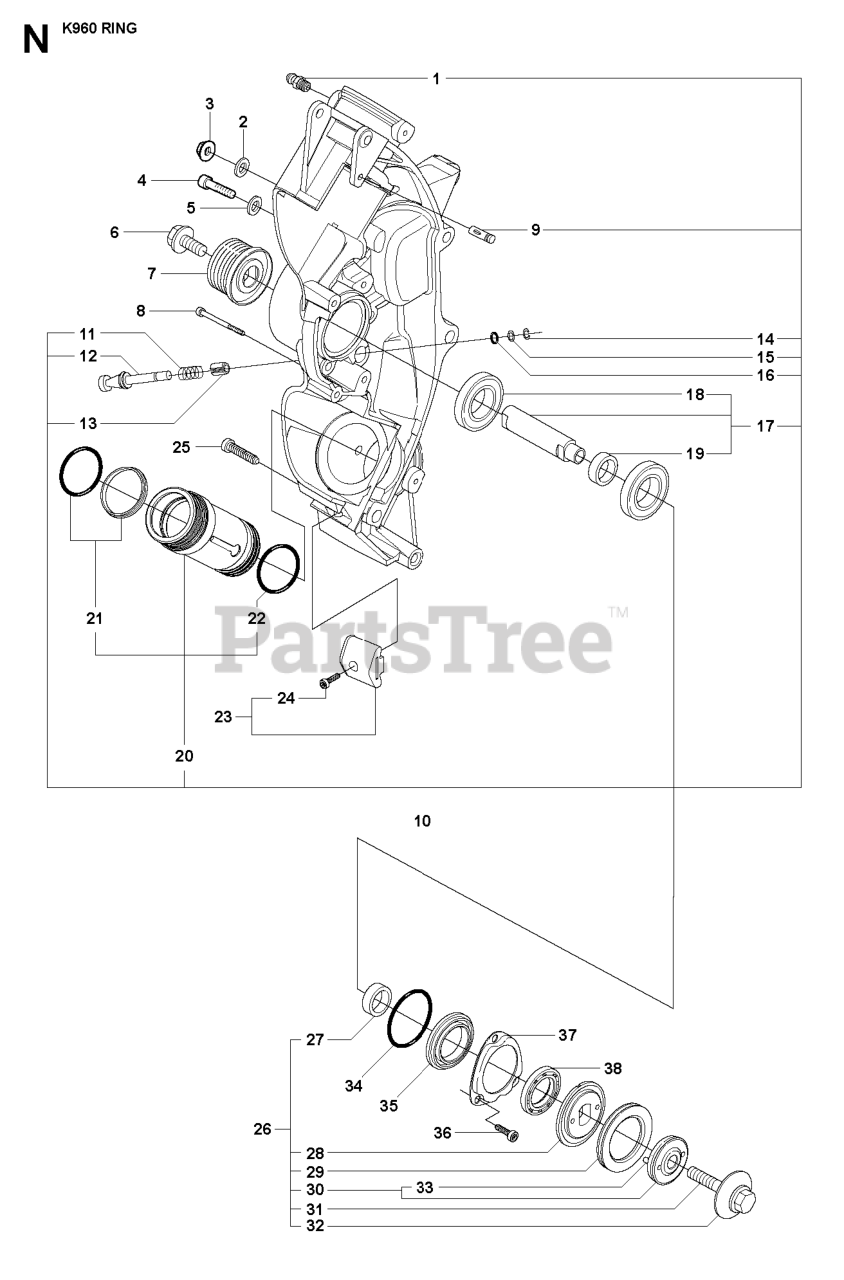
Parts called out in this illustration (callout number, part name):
1	GREASE NIPPLE
2	NUT M8 FLANGE
3	WASHER LOCK 8.7X16.6X2.5 ZN FL
5	WASHER LOCK 8.7X13.5X2.5 ZN FL
8	SCREW ITXSCM M5X80/25 T27 12.
9	GROOVED PIN
13	SPRING PIN
14	SEEGER CLIP
18	BALL BEARING
20	SLEEVE COMPLETE
29	GEAR WHEEL
32	WASHER
33	SPIRAL PIN 4X12
38	SEALING RING 20X30X5
